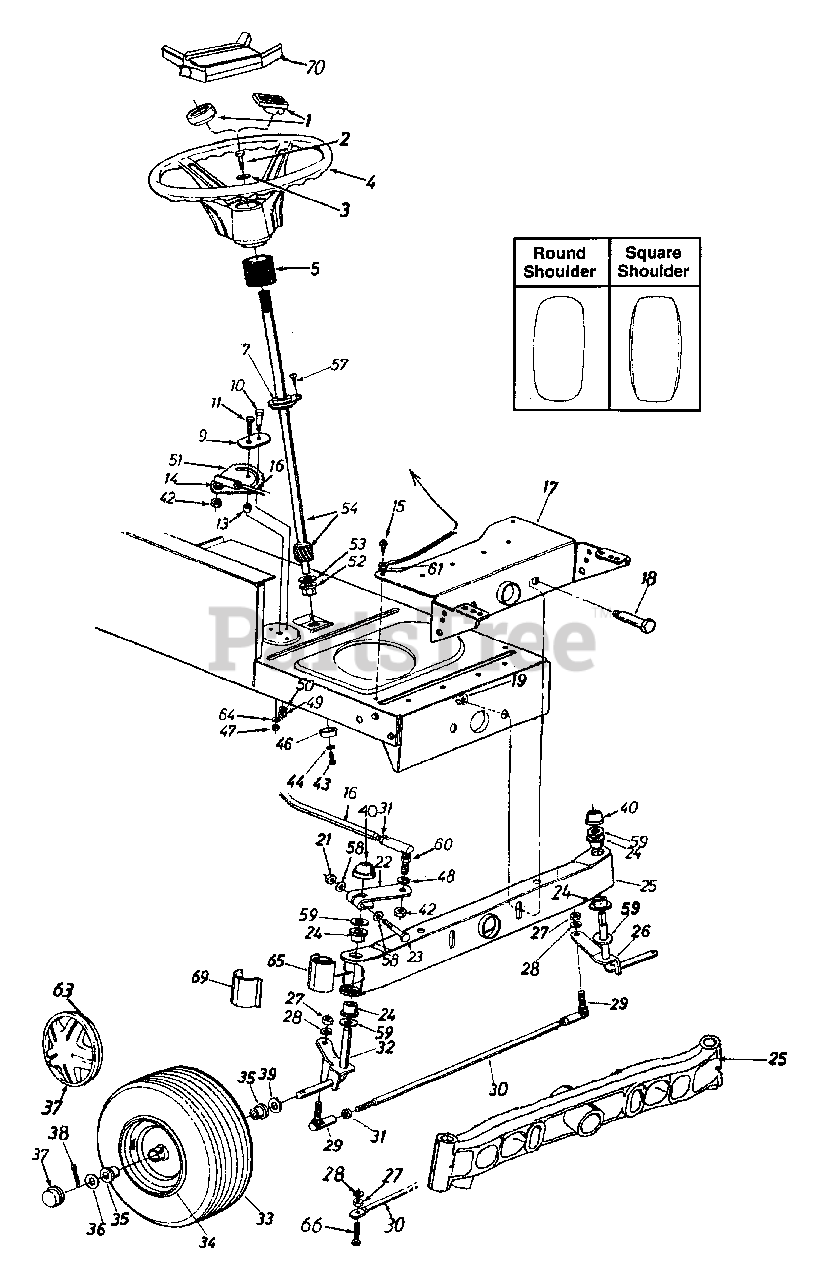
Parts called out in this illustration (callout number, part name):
1	Steering Wheel Cap
2	Hex Bolt 5/16-18 x 1" Lg.
3	Belleville Wash. .345" I.D.
4	Steering Wheel (3 Spoke)
5	Steering Bellow-4.5" (Style A)
7	Flange Bearing .628" I.D. x 1.36 O.D.
9	Retainer Plate
10	Shoulder Bolt .437 x .35 Lg. 5/16-18
11	Hex Bolt 3/8-24 x 1.0" Lg. (Gr. 5)
13	Spacer .380" I.D. x .625" O.D. x
14	L-Wash. 3/8" I.D. (H.D.)
15	Hex Wash. Hd. Self-Tap Scr.
16	Steering Drag Link
18	Shoulder Bolt
19	Flanged L-Nut 3/8-16 Thd.
21	Hex L-Nut 5/16-24 Thd.
22	Steering Arm Front Axle
23	Hex Bolt 5/16-24 x 2.25" Lg.
24	Hex Flg. Brg. .632 I.D.
26	Front Axle Ass'y-L.H. 15" X 6" (Round & Square Shoulder)
26	Front Axle Ass'y-L.H. (46" Deck) 15" X 6" (Round & Square Shoulder)
27	Hex Nut 3/8-24 Thd.
28	L-Wash. 3/8" I.D.
29	Ball Joint 3/8-24 Thd.
30	Tie Rod (Adjustable)
31	Hex Jam Nut 3/8-24 Thd.
32	Front Axle Ass'y-R.H. 15" X 6" (Round & Square Shoulder)
32	Front Axle Ass'y-R.H. (46" Deck) 15" X 6" (Round & Square Shoulder)
36	Fl-Wash 635 I.D. x 1.59" O.D.
37	Front Wheel Hub Cap
38	Cotter Pin 1/8" Dia. x 1.25"
39	Fl-Wash. .640" I.D. x 1.24" O.D.
40	Push Cap 5/8" Dia. Rod
42	Hex Jam Nut 3/8-24 Thd.
43	Hex Patch Bolt 5/16-18 x .62"
46	Cap
47	Hex Cent. L-Nut 3/8-24 Thd.
48	L-Wash. 3/8" I.D.
49	Hex Cent. L-Nut 5/16-18 Thd.
50	L-Wash. 5/16" I.D.
51	Steering Gear Segment
52	Hex Fig. Brg. .634 I.D.
53	Fl-Wash. (Hardened)
54	Steering Shaft
57	Oval Hd. Cr.-Sunk Scr. (Style A)
58	Wave-Wash. .32" I.D. x .60" O.D.
59	Fl-Wash. (Hardened)
60	Drag Link Ball Joint 7/16-20 Thd.
63	Spring Clip (Used w/Spoked Hub Cap)
64	Bell-Wash. .39" I.D. x 1.38" O.D.
65	Pivot Bar End Cap
66	Hex Bolt 3/8-24 x 1.5" Lg. (Gr. 5)
69	Axle Cap
70	Steering Wheel Insert
